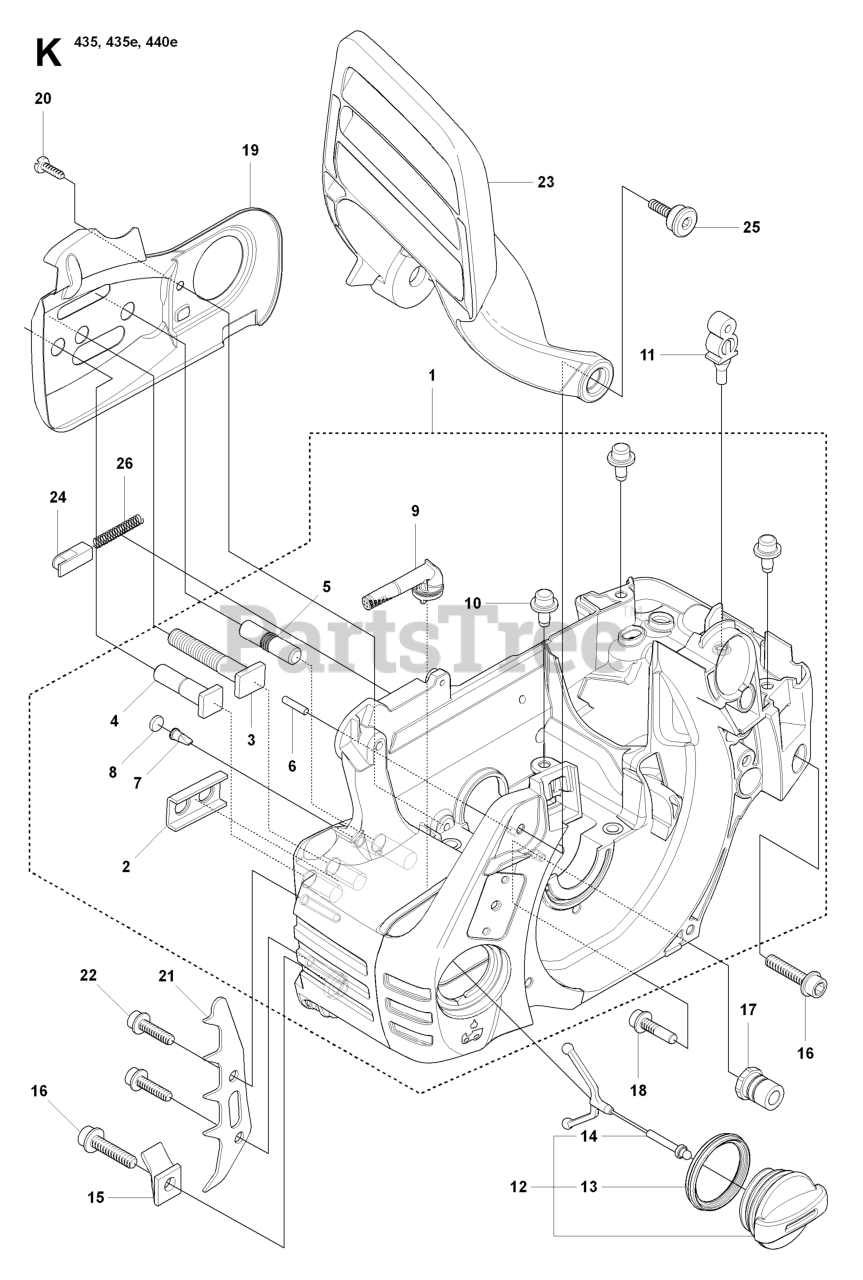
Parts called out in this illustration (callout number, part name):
1	CRANKCASE ASSY
2	STIFFENING PLATE
7	VALVE-CHECK (DUCKBILL)
8	PLUG
9	OIL SCREEN
11	SUPPORT
12	TANK CAP ASSY
13	SEALING
15	CHAIN CATCHER
16	SCREW IHSCFT
17	LATERAL SUPPORT
18	SCREW IHSCFT
19	CHAIN GUIDE PLATE
21	SPIKE INNER
23	HAND GUARD
25	SCREW
26	LOCK SPRING
